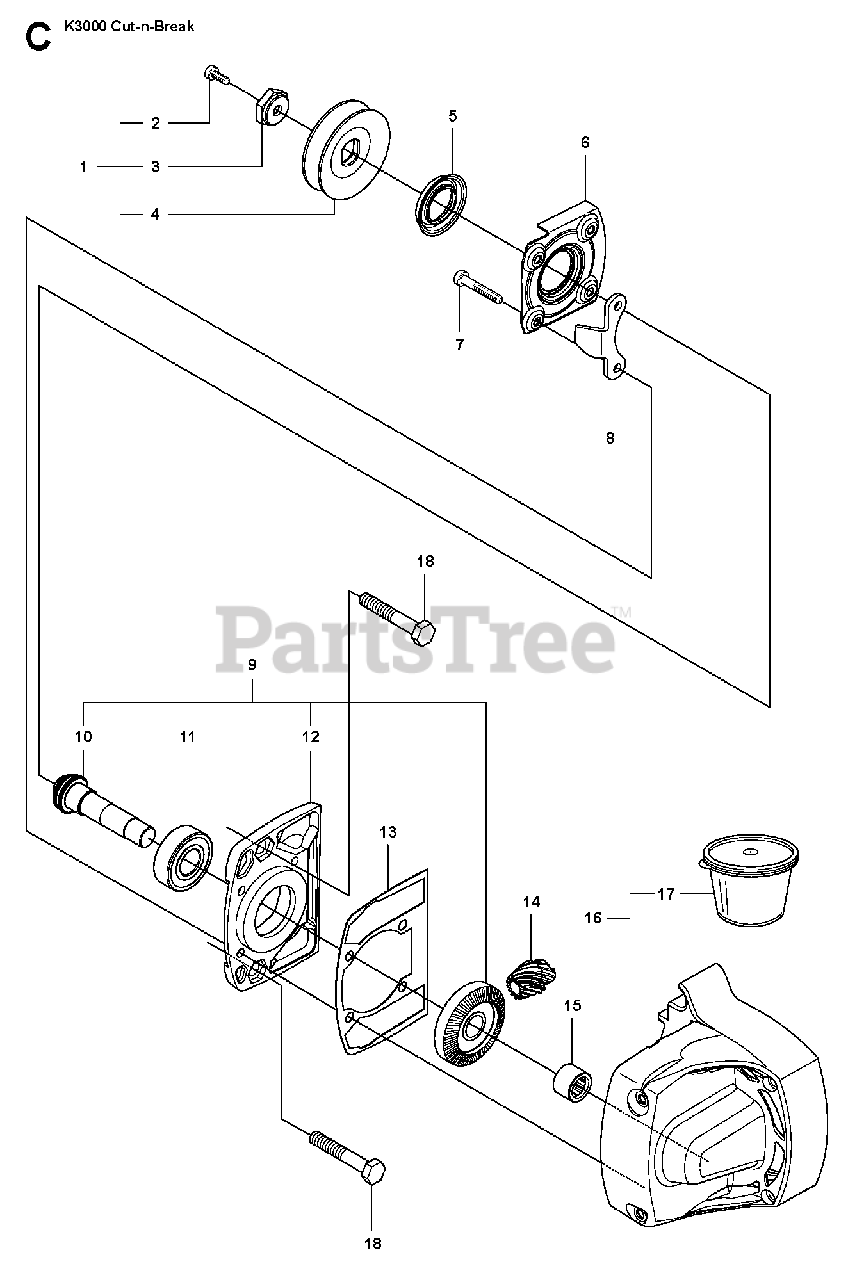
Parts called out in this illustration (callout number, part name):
1	DRIVING PULLEY ASSYIncl. 2 - 4
2	SCREW ITXSCM
7	SCREW ITXSCM
9	GEAR SETIncl. 10 - 12
11	BALL BEARING
15	NEEDLE BEARING
17	GREASE
